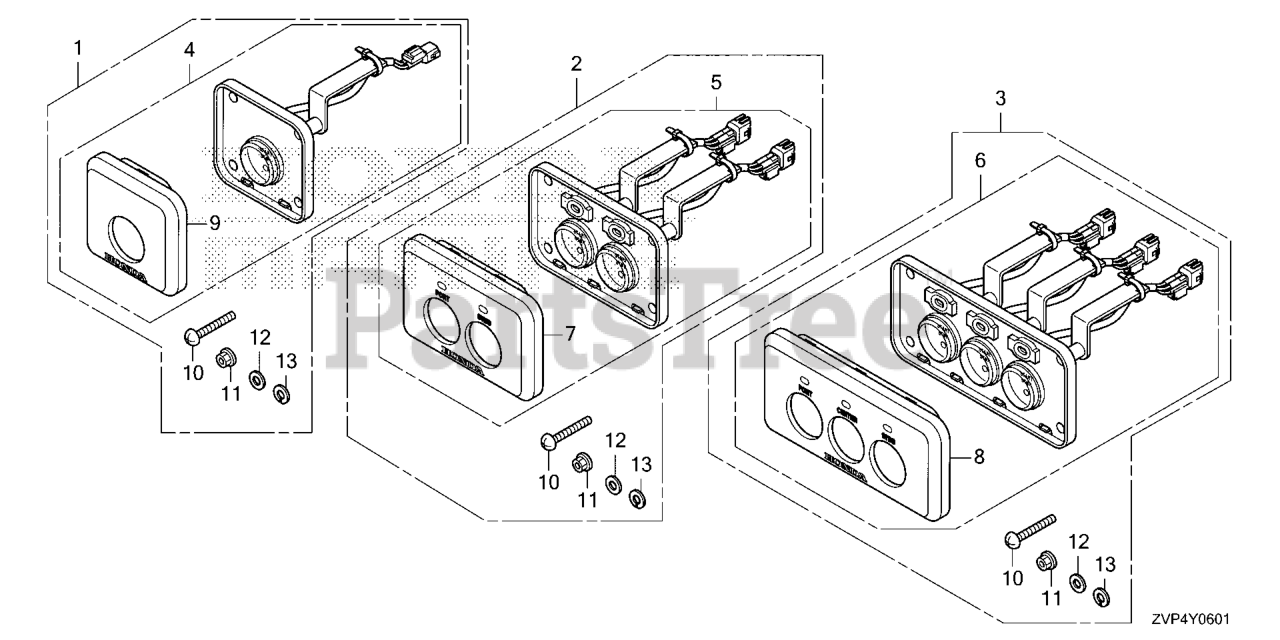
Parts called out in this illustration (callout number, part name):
1	PANEL KIT, START STOP SWITCH (ALL)
1	PANEL KIT, S/S SW
2	PANEL KIT, S/S SW
3	PANEL KIT, S/S SW
4	PANEL ASSY., START STOP (ALL)
4	PANEL ASSY., START STOP (SINGLE)
5	PANEL ASSY., START STOP (TWIN)
6	PANEL ASSY., START STOP (TRIPLE)
7	PANEL, START STOP (TWIN)
8	PANEL, START STOP (TRIPLE)
9	PANEL, START STOP (ALL)
9	PANEL, START STOP (SINGLE)
10	SCREW, PAN (5X40) DUAL QTY = (8) (SINGLE)
11	NUT, FLANGE (5MM)
12	WASHER, PLAIN (5MM)
13	WASHER, SPG (5MM)
